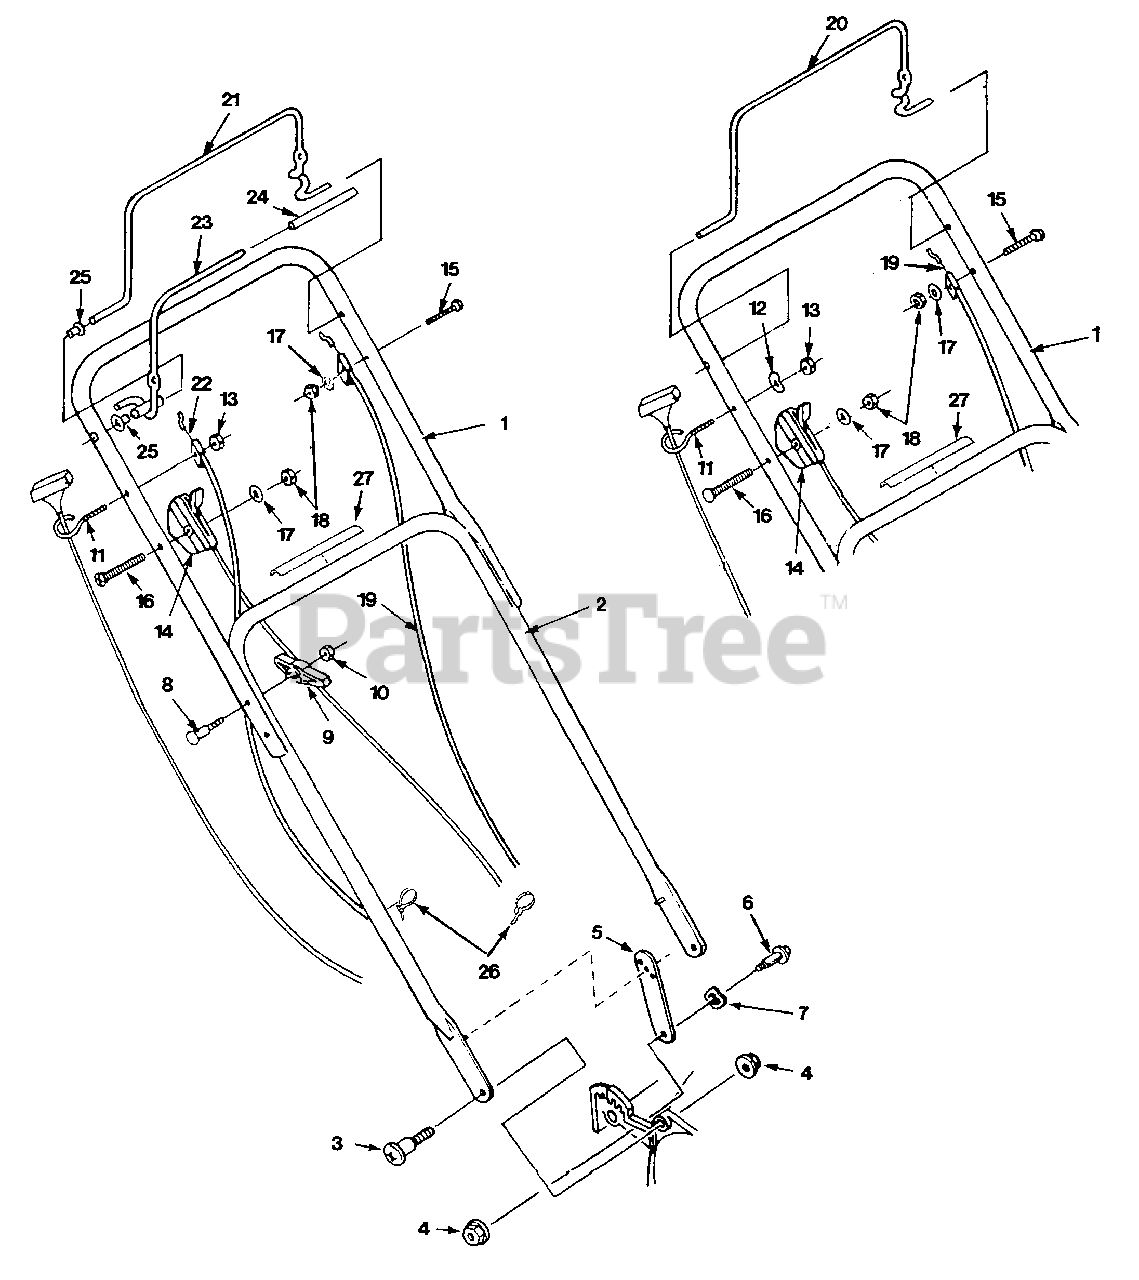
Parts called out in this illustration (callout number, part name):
1	Handle - upper
2	Handle - lower
3	Bolt-handle 5/16-18
4	Nut - hex 5/16-18 flng lock
5	Support - handle
6	Bolt - handle support 5/16-18
7	Washer - wave 5/16
8	Bolt - carriage 5/16-18 x 2-1/4
9	Knob - handle, plastic
10	Nut - hex 5/16-18
11	Eyebolt-starter rope 1/4-20
13	Nut - hex 1/4-20 lock
14	Control - throttle w/cable
16	Screw - truss hd 1/4-20 x 1-3/4
17	Washer - star 1/4
18	Nut - hex 1/4-20
19	Cable - engine/blade control
20	Bail - engine/blade control
21	Bail - engine/blade control
22	Cable - traction drive
23	Bail - traction drive
24	Sleeve - drive bail
25	Bushing - drive bail
26	Cable Tie
27	Decal - starting instructions
